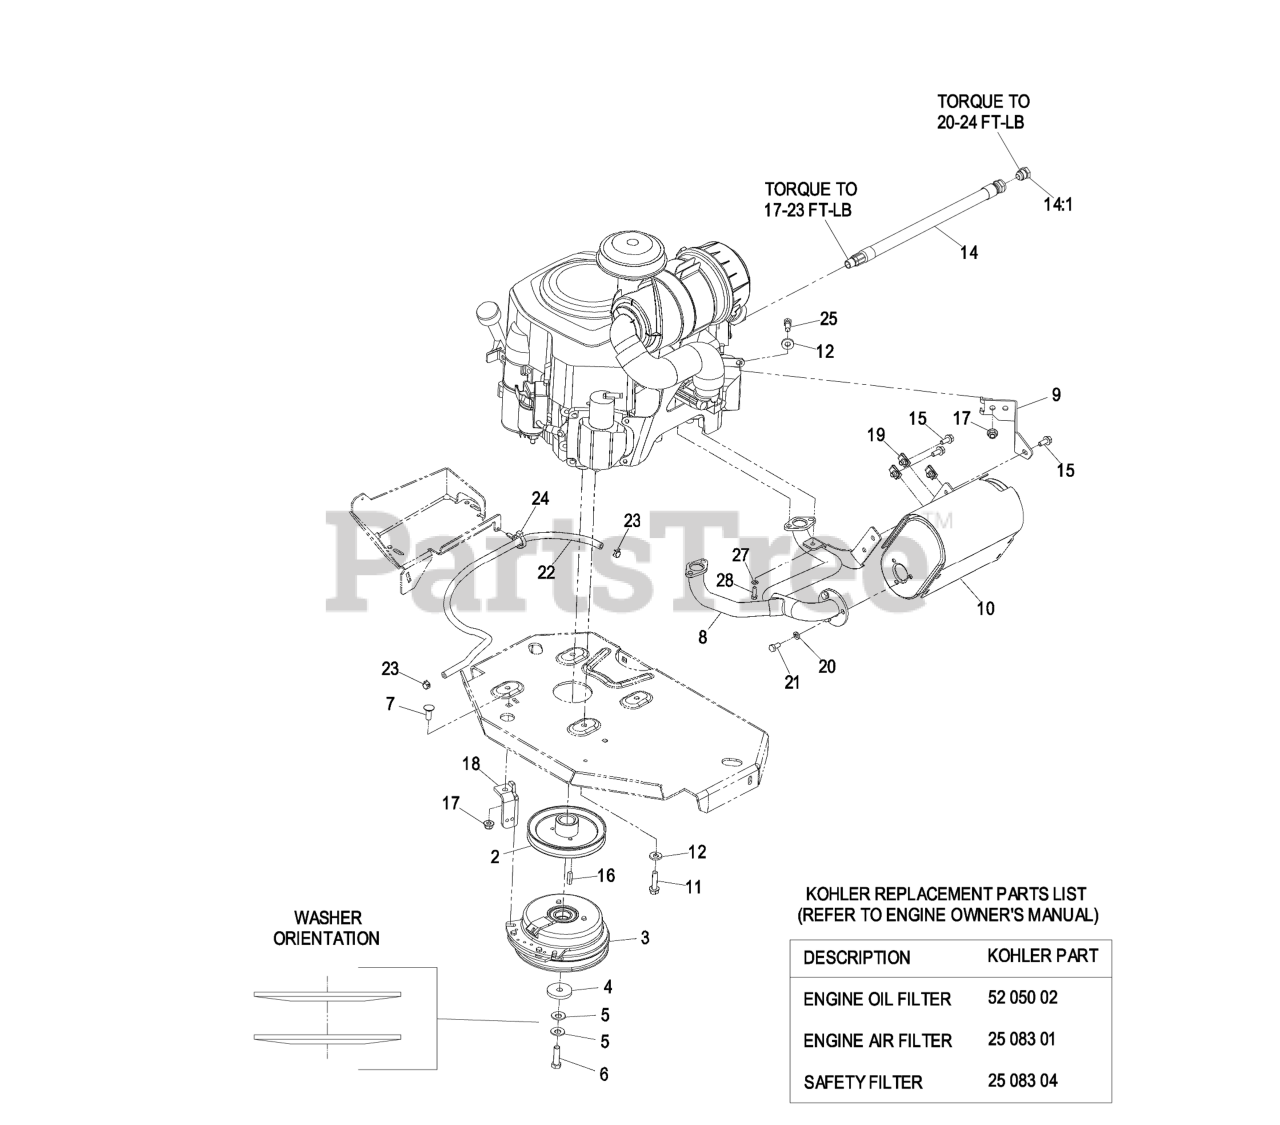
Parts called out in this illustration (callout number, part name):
2	SHEAVE
4	WASHER-CLUTCH
5	WASHER-SPRING
6	SCREW-HH 7/16-20 X 1 1/2 W/LOCTITE
7	SCREW-CARR
10	MUFFLER-ENGINE
11	SCREW-HWH
12	WASHER-BELLEVILLE
15	SCREW-HHF
17	NUT-HF, NI
18	ANCHOR-CLUTCH
20	WASHER-LOCK
21	SCREW-HH
22	HOSE-FUEL
23	CLAMP-HOSE
24	CLAMP-HOSE
25	SCREW-HH
27	WASHER-SPRING
28	SCREW-HH
